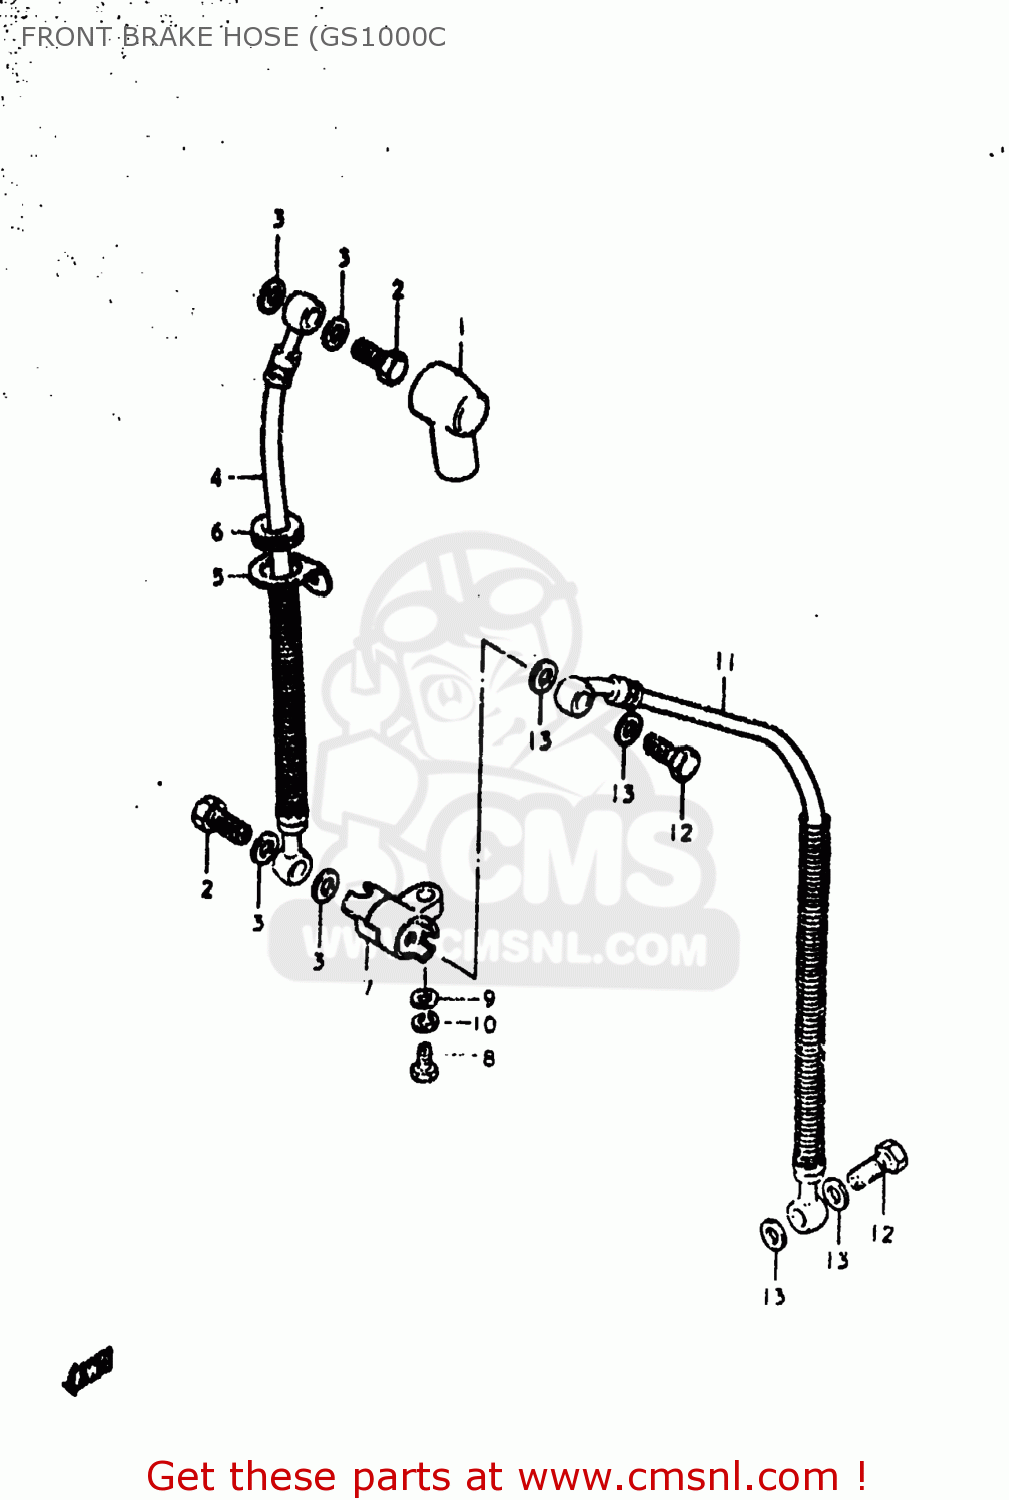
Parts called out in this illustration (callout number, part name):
1	BOOT,MASTER CYLINDER
2	BOLT UNION
3	WASHER
4	HOSE,FRONT BRAKE
5	GUIDE,BRAKE HOSE
6	GROMMET
7	JOINT,BRAKE HOSE
8	BOLT
9	WASHER
10	LOCK WASHER
11	HOSE,FRONT BRAKE
12	BOLT UNION
13	WASHER
